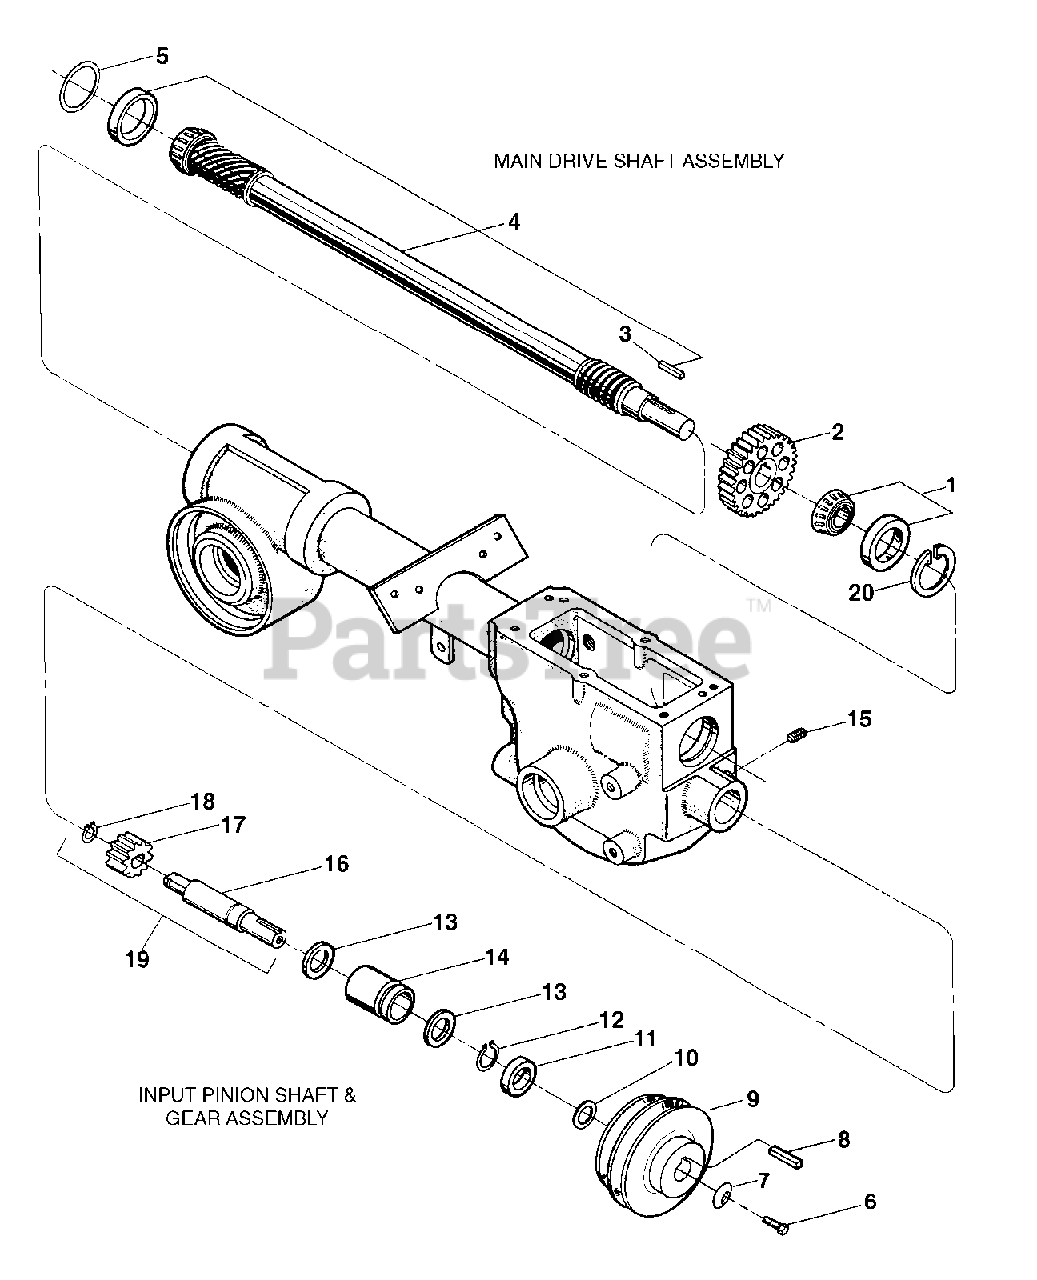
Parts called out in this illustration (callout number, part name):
1	Bearing, Tapered Roller with Race
2	Spur Gear
3	Key, 3/16 sq. x 1
4	Main Drive Shaft
5	Shim, Rear Bearing Cap, .010" thick
5	Shim, same as above, but .030" thick
5	Shim, same as above, but .005" thick
6	Hex Hd. Screw, 5/16-24 x 1-1/8
7	Washer, Disc Spring (concave surface faces pulley)
8	Key, 3/16 sq. x 1-1/2
9	Transmission Drive Pulley
10	Support Washer
11	Oil Seal, Input Pinion Shaft
12	Retaining Ring (external)
13	Thrust Washer
14	Bushing
15	Set Screw, 5/16-18 x 3/8
16	Input Pinion (steel shaft)
17	Input Pinion Gear
18	Retaining Ring (external)
19	Pinion Assy.
20	Retaining Ring (internal)
